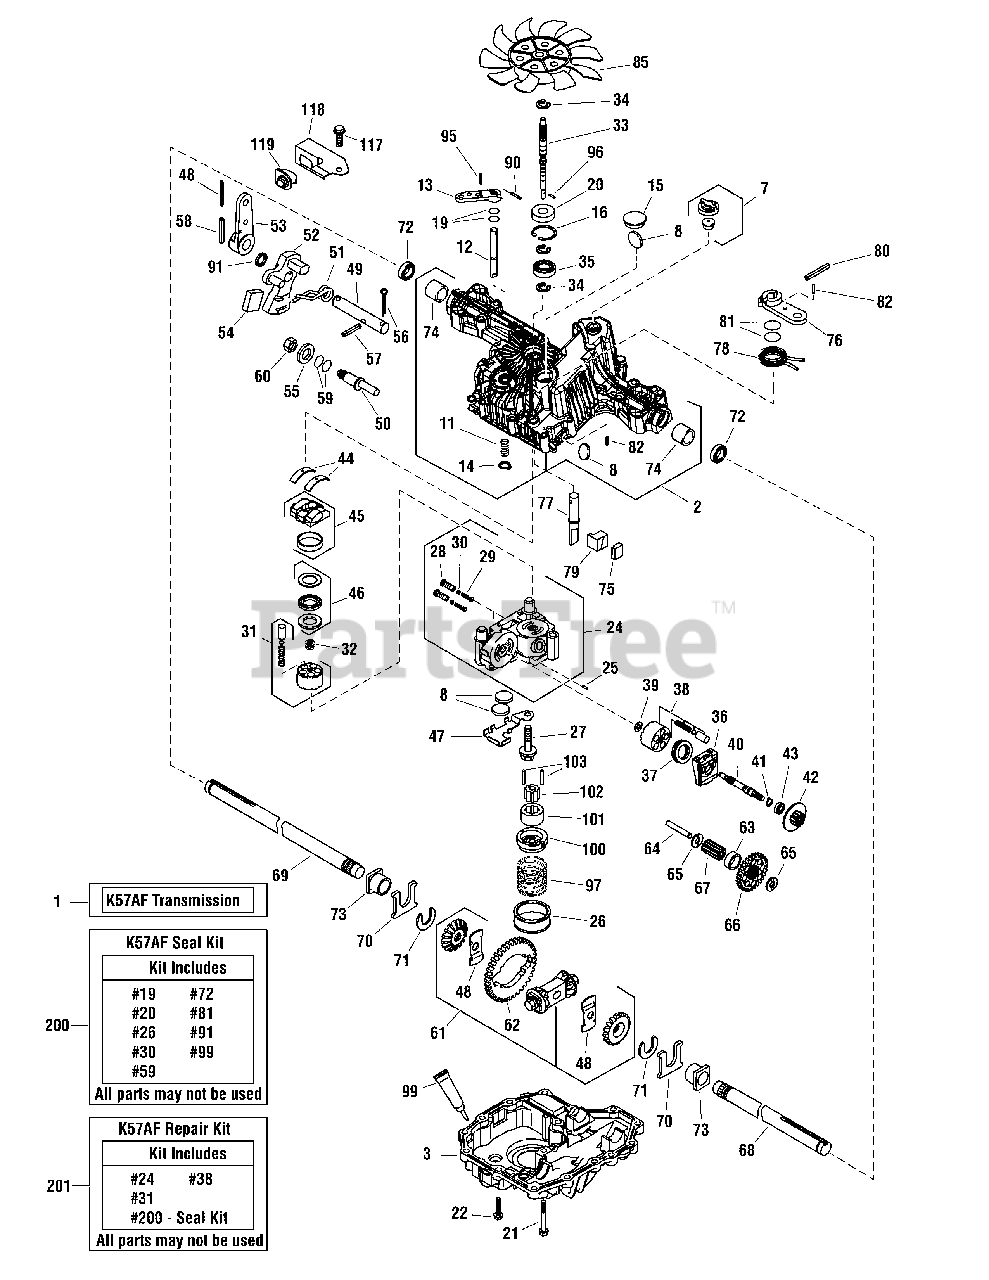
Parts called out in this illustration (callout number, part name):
1	TRANSMISSION, Tuff Torq, K57AF
2	* KIT, Upper Case
3	* LOWER CASE
8	MAGNET 28 * 3.5
12	BYPASS SHAFT A
13	BYPASS LEVER
15	SEALING CAP 30
16	SNAP RING C 35
20	SEAL TC 153507
22	SCREW, Tapping, 8 x 30
24	* KIT, CENTER CASE H/FILTER IDS
25	PIN 3 * 9.8
29	* IDS SPRING
31	* KIT, Cylinder Block (MOTOR)
34	E-RING
35	BEARING 6202C3
36	* MOTOR HOUSING
37	* THRUST (BALL) BEARING
39	WASHER 12 * 24 * 1
40	MOTOR SHAFT
41	SNAP RING S15
42	BRAKE DISC/MOTOR GEAR (10T)
43	6202 BEARING
44	THRUST PLASTIC
45	* SWASH PLATE CMP
46	* KIT, Thrust Bearing (Pump)
47	* MAGNET HOLDER
48	THRUST WASHER
49	* CONTROL SHAFT
50	* FULCRUM
51	* SPRING, Torsion
52	* CONTROL ARM A
53	CONTROL LEVER C
54	* JERKY PLATE
56	COTTER PIN 1/8" * 3/4"
58	ROLL PIN 6 * 40
59	O-RING 1A P14
61	* KIT, Diff Gear
64	* REDUCTION SHAFT
65	WASHER 12 * 32 * 3.2
66	REDUCTION GEAR (38T)
68	AXLE SHAFT, LEFT
69	AXLE SHAFT, RIGHT
70	THRUST WASHER
72	SEAL 19 * 32 * 8
73	BUSHING 19 * 25
76	BRAKE LEVER
77	* BRAKE SHAFT
78	* SPRING, Brake Return
79	BRAKE ACTUATOR
80	SPRING PIN 5 * 32
82	SPRING PIN 4 * 16
86	WAVE WASHER
90	SPRING PIN 3.0A * 20
91	OIL SEAL 16 * 22 * .03
96	PIN 2.5* 9.8
97	* CHARGE SPRING
99	* SEALANT
100	PUMP CASE KIT
101	* ROTOR, Inner
102	* ROTOR, Outer
103	PIN 3.0 * 18
118	* SWITCH BRACKET
119	* SWITCH
200	SEAL KIT (K57A & K)
